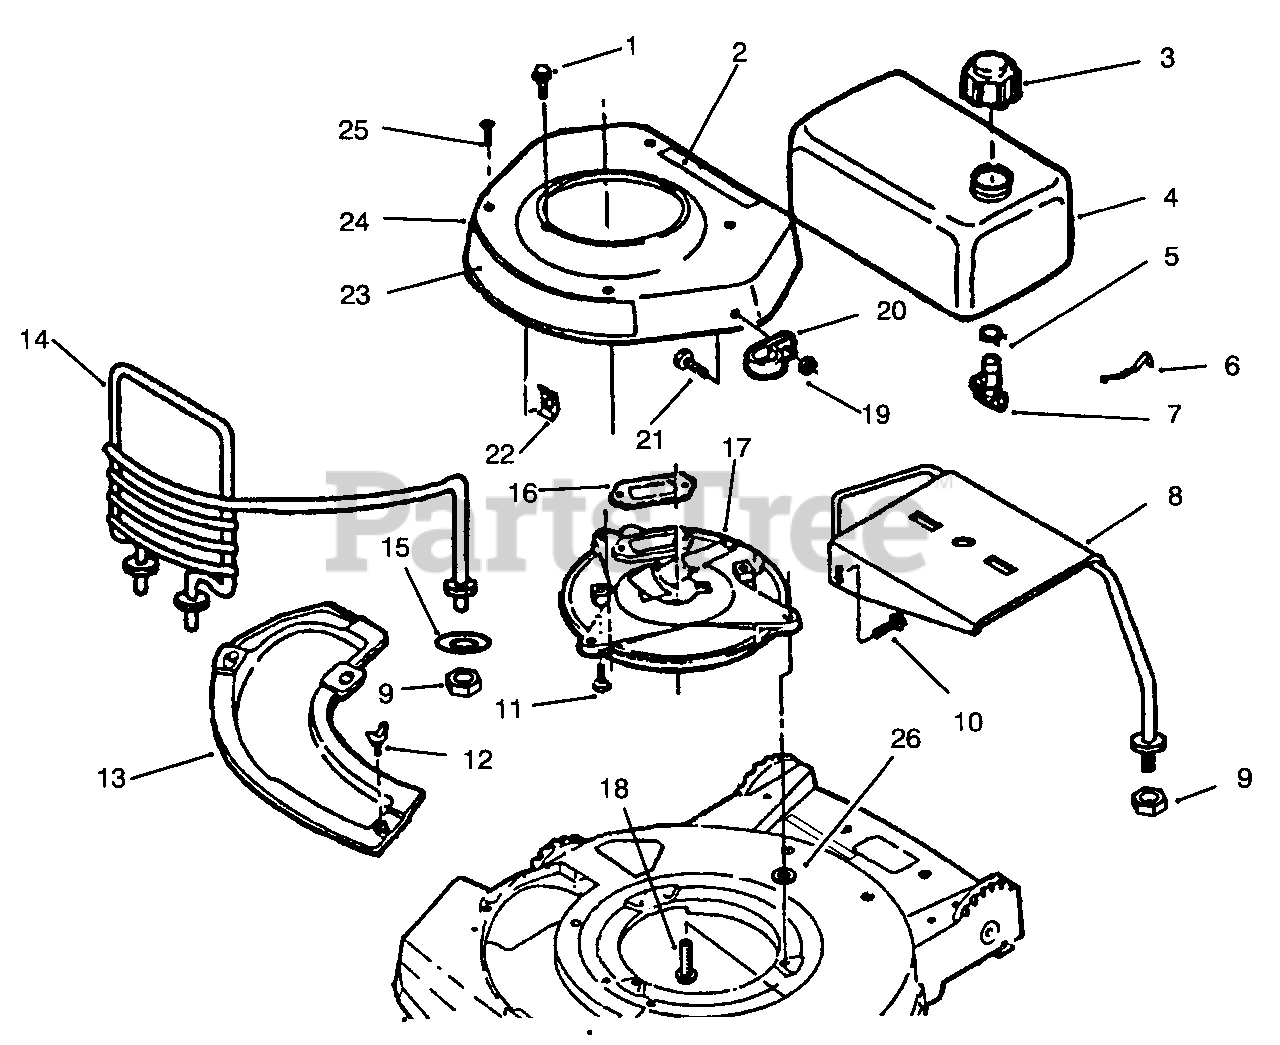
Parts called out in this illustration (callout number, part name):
1	Screw-Starter
2	Decal-Mixture, Fuel
3	Assembly-Cap, Fuel
4	Tank-Fuel
5	Clamp-Valve to Tank
6	Spring-Mount., Fuel Tank
7	Valve & Screen-Shut-Off
8	Bracket-Tank, Fuel
10	Screw-Hex Hd. Cap
11	Screw-Mumer Plate to Block
12	Screw-Wing
13	Plate-Cover
14	Guard-Engine
16	Gasket-Exhaust
17	Plate-Muffler
18	Screw-Muffler Plate to Housing
19	Nut-Lock
21	Screw-Clamp to Shroud
22	Retainer-Applique
23	Applique
25	Screw Shroud to Base
26	Washer-Flat
